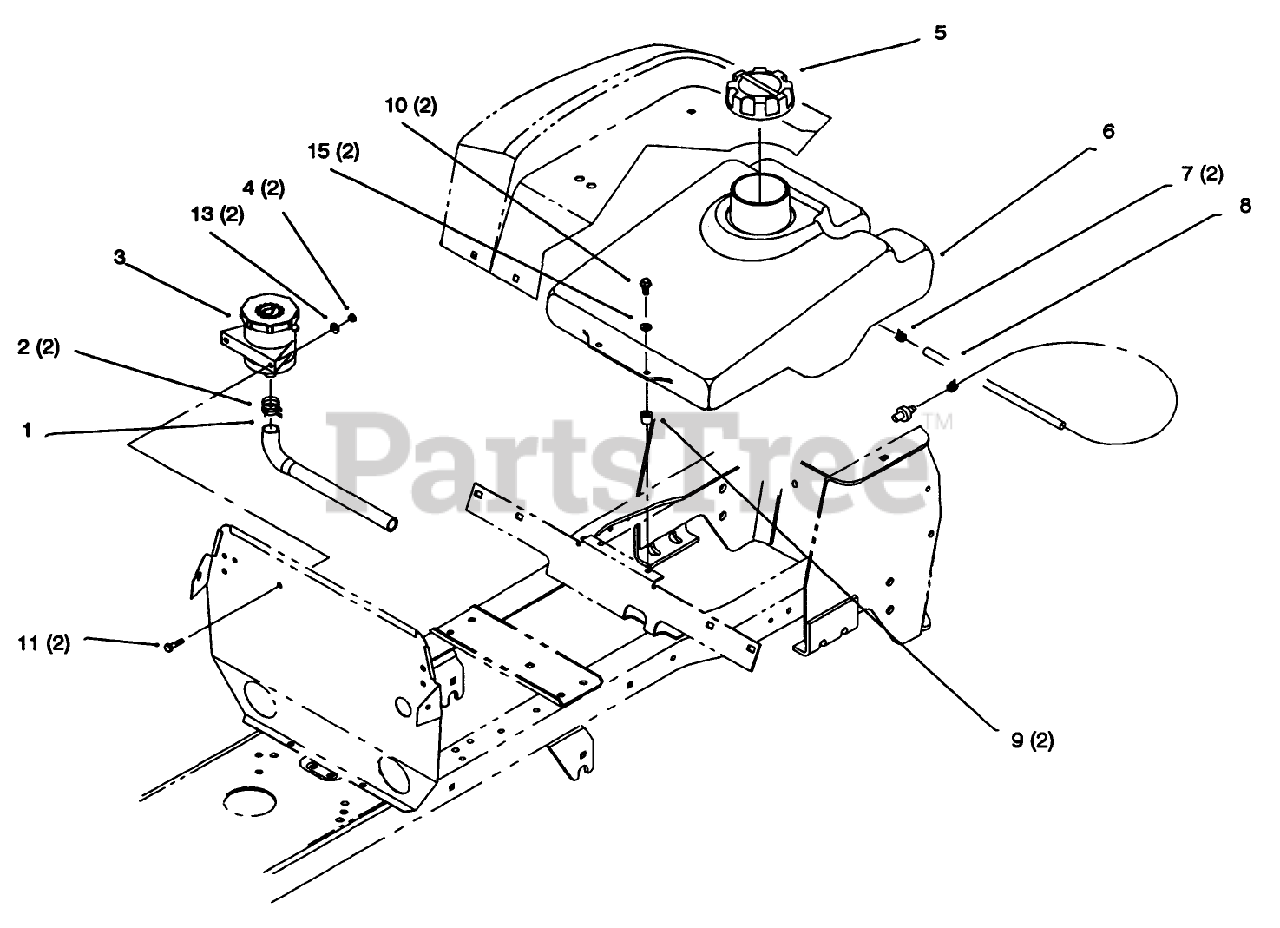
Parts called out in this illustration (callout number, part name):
1	HOSE - HYDRO
2	CLAMP-HOSE
4	NUT-LOCK, NI
5	GAS CAP ASM
7	CLAMP-HOSE
8	HOSE-FUEL
9	SPACER - FUEL TANK
10	SCREW-HH
10	SCREW-HWH
11	SCREW-HH
13	WASHER-FLAT
15	Washer-Flat (Only On: 72043, 72103, 72063, 72083)
